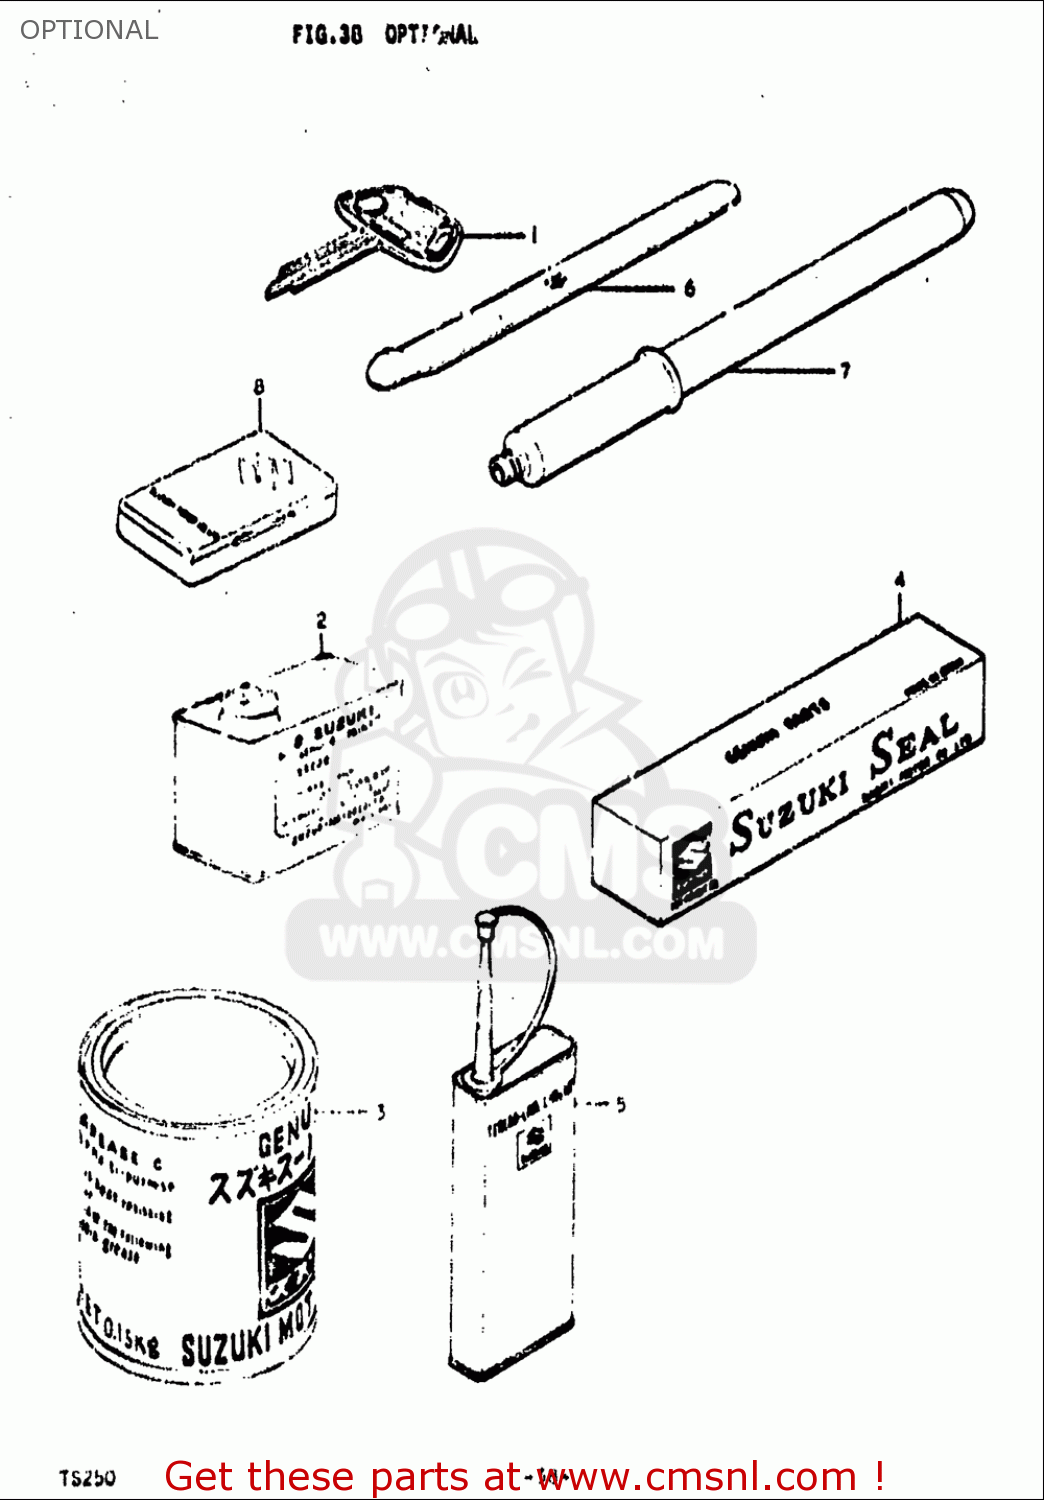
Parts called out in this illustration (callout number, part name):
3	GREASE(C)EP2 LITHIUM 150G
5	THREAD LOCK NO.1401 CLEAR 200G
7	LEVER,TIRE
